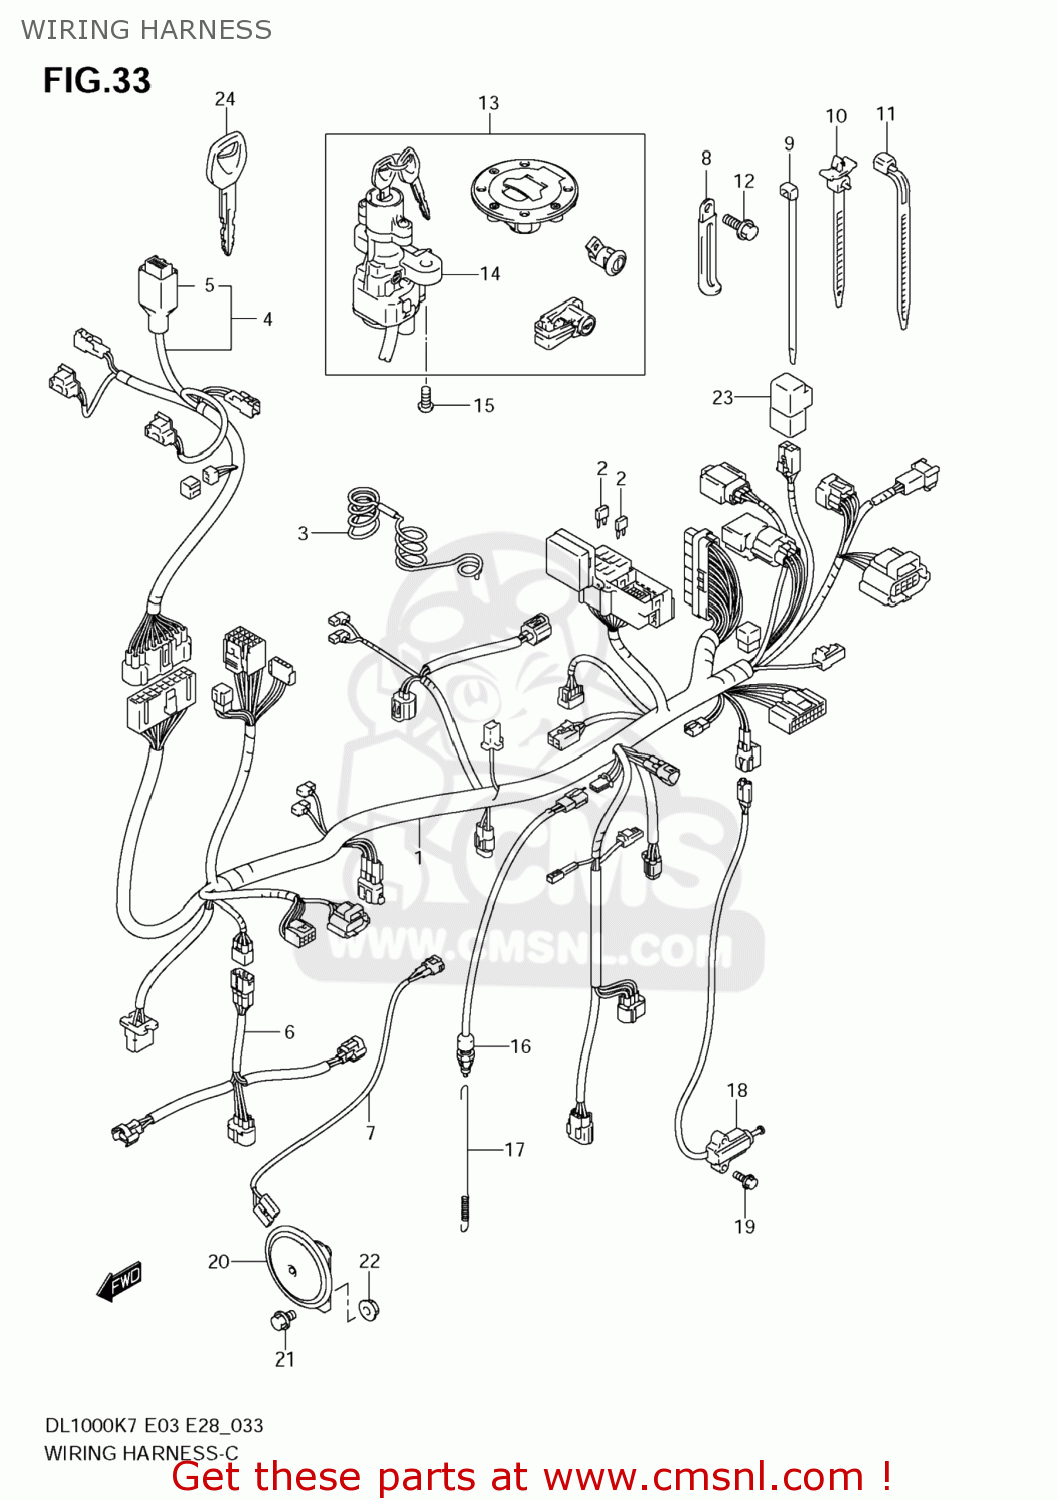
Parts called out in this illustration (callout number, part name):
1	HARNESS,WIRING NO.1
2	FUSE(10A)
3	GUIDE,WIRING HARNESS
4	HARNESS,WIRING NO.2
5	COVER,CONNECTOR
6	WIRE,INJECTOR LEAD
7	WIRE,HORN LEAD
8	CLAMP(L:45)
9	CLAMP(L:145)
10	CLAMP
11	CLAMP(L:95)
12	BOLT
13	LOCK SET
14	LOCK ASSY,STEERING
15	BOLT(8X20)
16	SWITCH ASSY,STOP LAMP
17	SPRING,STOP LAMP SWITCH
18	SWITCH ASSY,SIDE STAND
19	BOLT
20	HORN ASSY
21	BOLT
22	NUT
23	RELAY ASSY
24	KEY,BLANK
